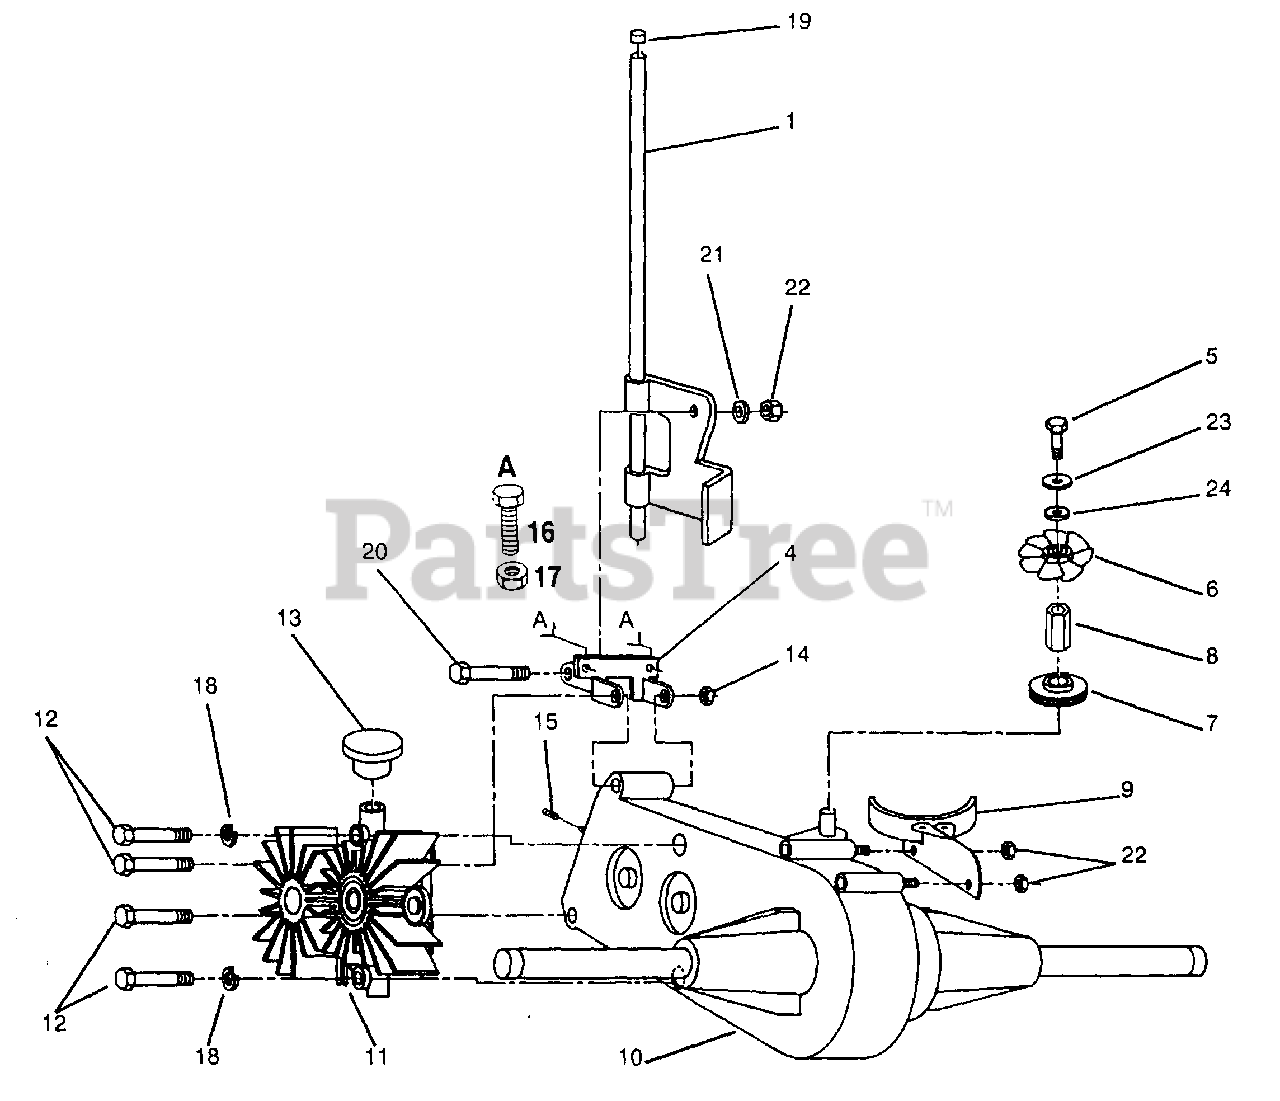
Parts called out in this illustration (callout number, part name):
1	Control, Asm., Free Wheel (AYP part number)
4	Bracket, Pnt. Mounting Differential (AYP part number)
5	Bolt, Hex Hd. 1/4 -20 UNC x 3/4 (AYP part number)
6	Fan, Hydro 8" (AYP part number)
7	Pulley, Transaxle (AYP part number)
8	Standoff, Fan Hydro (AYP part number)
9	Guard Assembly, Belt (AYP part number)
10	Differential Assembly (AYP part number)
11	Pump Assembly (AYP part number)
12	Bolt, Hex Fin. 5/16-18 UNC x 4.5 (AYP part number)
13	Reservoir Pump (AYP part number)
14	Nut, Crownlock 5/16 - 18
15	Spring, Compression (AYP part number)
16	Bolt, 3/8-16 x 3/4 (AYP part number)
17	Nut 3/8-16 UNC
18	Washer Lock Hvy. Helical (AYP part number)
19	Cap, Plunger (AYP part number)
20	Bolt Shoulder 1/4-20 UNC (AYP part number)
21	Washer, Nylon (AYP part number)
22	Nut, Crown lock 1/4-20 UNC (AYP part number)
23	Washer 9/32 x 1-1/4 x 16 ga. (AYP part number)
24	Washer Lock, Hvy., Helical (AYP part number)
